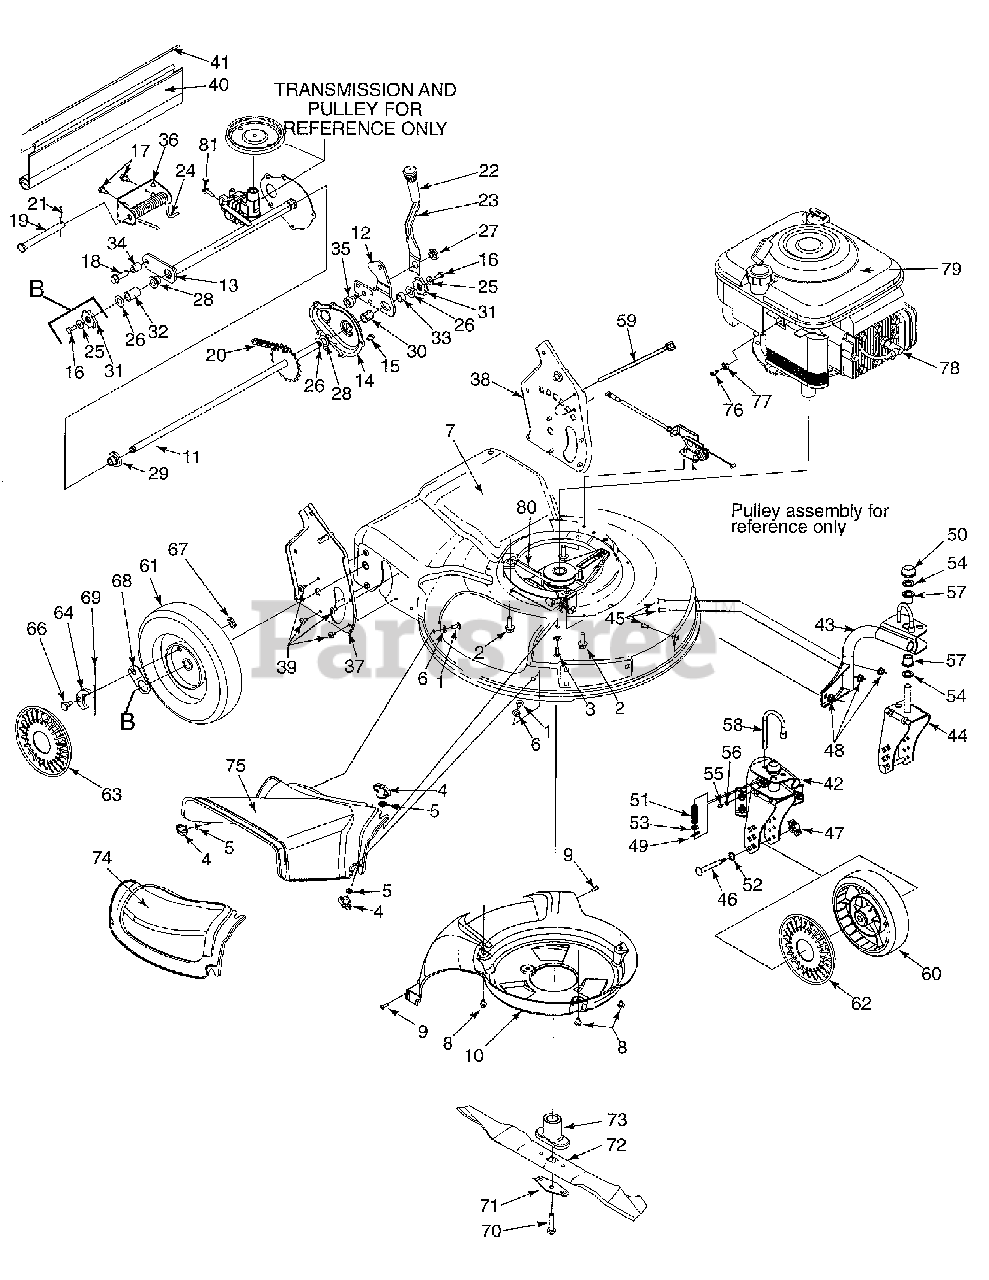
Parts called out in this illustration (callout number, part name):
1	Carriage Screw 1/4-20 x .62
2	Screw TT 3/8-18:1.00
3	Carrriage Bolt 1/4-20 x .750
4	Wing Nut
5	Push Nut
6	Flat Washer .334 I.D. x .62 O.D. x .03
9	Screw HL 1/2-14 x .750
10	Rear Baffle
11	Rear Axle Ass'y.
12	Rivot Arm, Rear
16	Hex Screw 1/4-20 x .620 Gr.5
17	Hex Screw AB 1/4-14 x .625
18	Hex Screw 3/16 x 1.25
19	Clevis Pin
20	Chain: Endls #48
21	Cotter Pin
23	Spring Lever
24	Torsion Spring
25	Bell Washer
26	Flat Washer
27	Shoulder Nut .625 dis x .165
28	Flange Bearing
29	Flange Bearing
30	Slev. Bearing
31	Ratchet Wheel
32	Spacer
33	Spacer
34	Spacer
35	Shoulder Spacer
40	Trail Shield
41	Trail Shield Wire
45	Carriage Bolt 5/16-18 Gr.5
46	Axle, Caster
47	Wing Nut
48	Lock Nut 5/16-18 Gr. 5
49	Internal Cotter Pin
50	Push Cap
51	Compression Spring
52	Wave Washer
53	Flat Washer .330 I.D. x .630 x .06
54	Flat Washer 5/8 I.D. x 1.0 O.D.
55	Lube Fitting
56	Flat Washer .203 I.D. c .403 O.D.
57	Flange Bearing
58	Front Wheel Lock Pin
59	Cabel Tie
60	Caster Wheel 7 x 2
61	Wheel Ass'y. Rear 9 x 2
62	Hub Cap
63	Hub Cap Radial
64	Pawl RH
66	Shoulder Screw
67	Weld Nut
68	Ratchet Pawl Plate
69	Ratchet Spring
70	Hex Bolt
71	Blade Bell Support
72	Mulching Blade
73	Blade Adapter
74	Mulching Cover
75	Side Discharge Chute
76	Hex Scr. Slt.Wash. .620
77	Casing Clamp, Throttle
78	Spark Plug (Champion)
79	Engine
80	Drive Belt
81	Hex Screw 5/16-18
